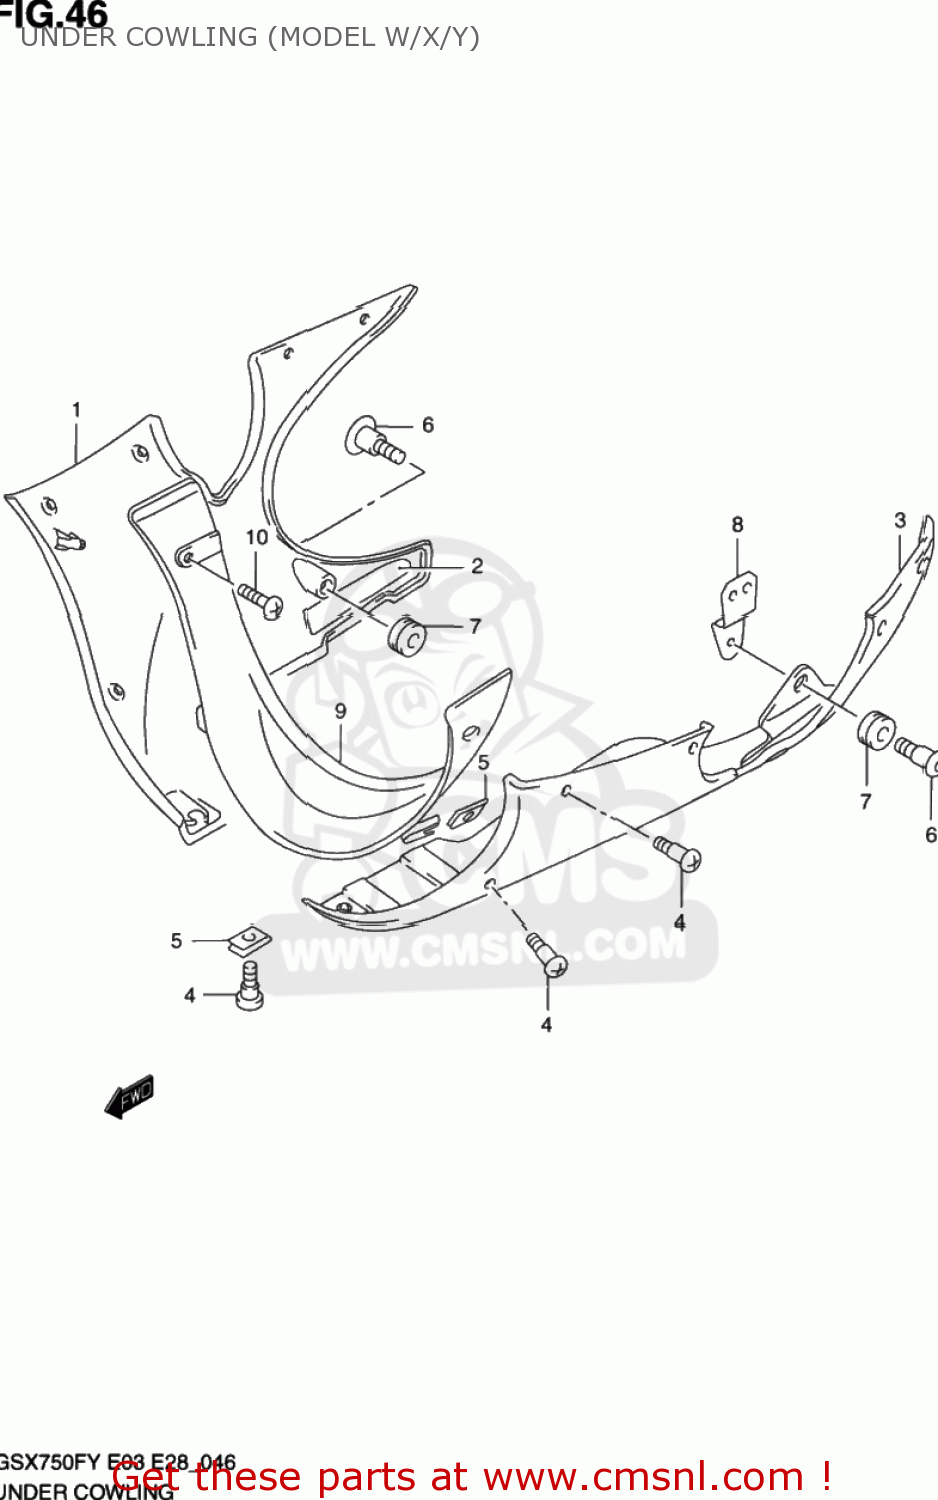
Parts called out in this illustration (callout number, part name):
1	COWLING,UNDER,R(GRAY)
2	SHIELD,COWLING UNDER,R NO.1
3	COWLING,UNDER,L
4	SCREW(5X16)
5	NUT,COWL
6	SCREW(6X20)
7	CUSHION
8	BRACKET,UNDER COWL,L & FRAME
9	COWLING,UNDER CTR
10	SCREW
